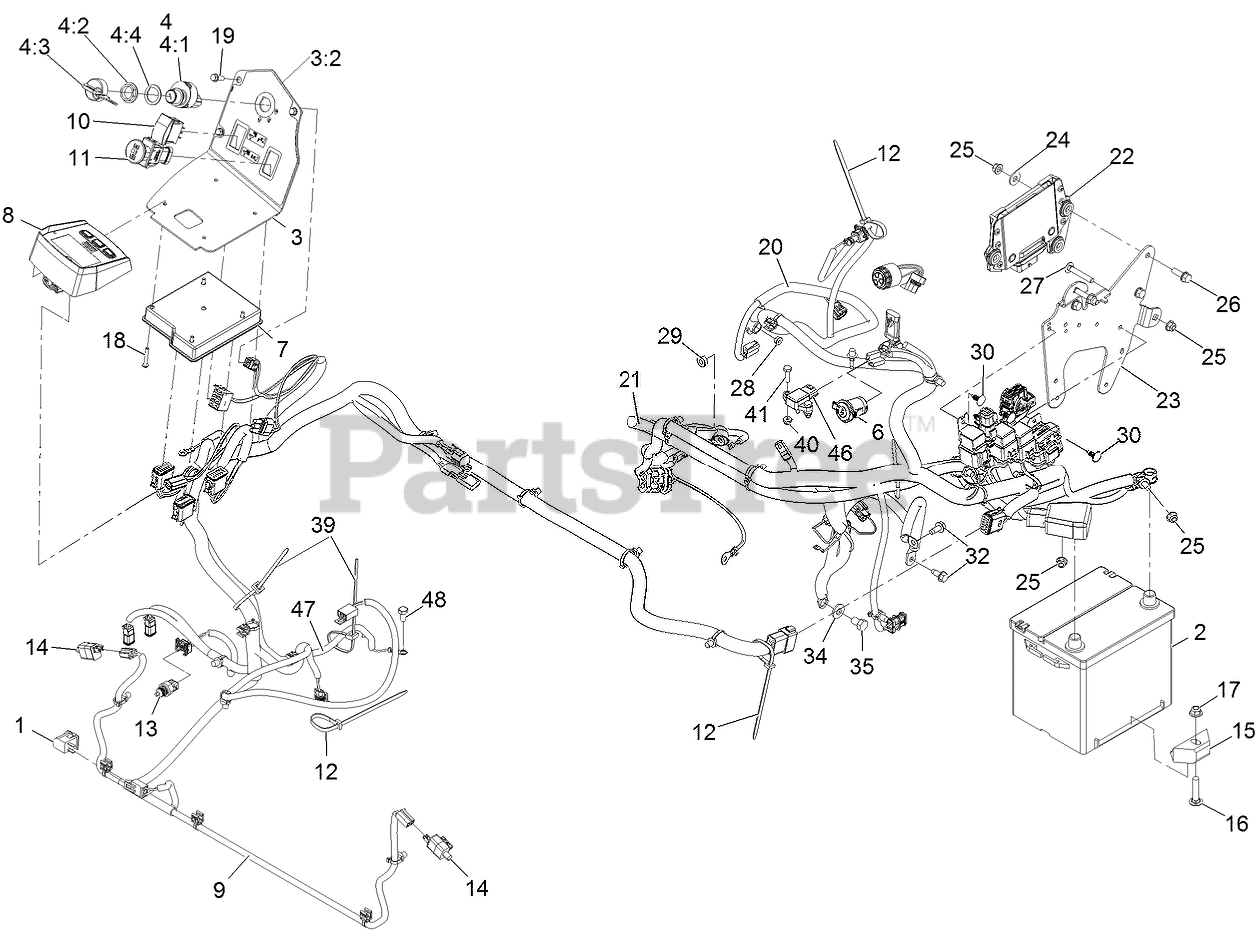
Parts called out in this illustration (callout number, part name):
1	SWITCH-BAIL
2	Battery-Dry
3	Console ASM
3:2	DECAL-CONTROL PANEL
4	IGNITION SWITCH ASM
4:1	Switch-Ignition
4:2	NUT-MOUNTING
4:3	IGNITION KEY SET
4:4	WASHER-BACKUP
6	PORT-POWER, 12V
7	Module-Mcu
8	Module, Ldu
9	HARNESS-WIRE
11	SWITCH-PTO, SEALED
12	TIE-PLASTIC
13	SENSOR-TEMPERATURE
15	RETAINER-BATTERY
16	SCREW-CARR
17	NUT-HF, NI
18	SCREW-PPH
19	SCREW-HWH
20	HARNESS-WIRE
21	CABLE-BATTERY
22	ECU ASM
23	BRACKET-MOUNT, ECU
24	WASHER-FLAT
25	NUT-HF, NI
26	SCREW-HHF
27	BOLT-CARR
30	PLUG-PLASTIC
32	Screw-HWH 5/16-18 X 3/4 Tf
34	WASHER-BELLEVILLE
35	SCREW-HH
39	TIE-CABLE
41	SCREW-HH
46	SENSOR-ATM
47	HARNESS-WIRE, JUMPER
48	BOLT
